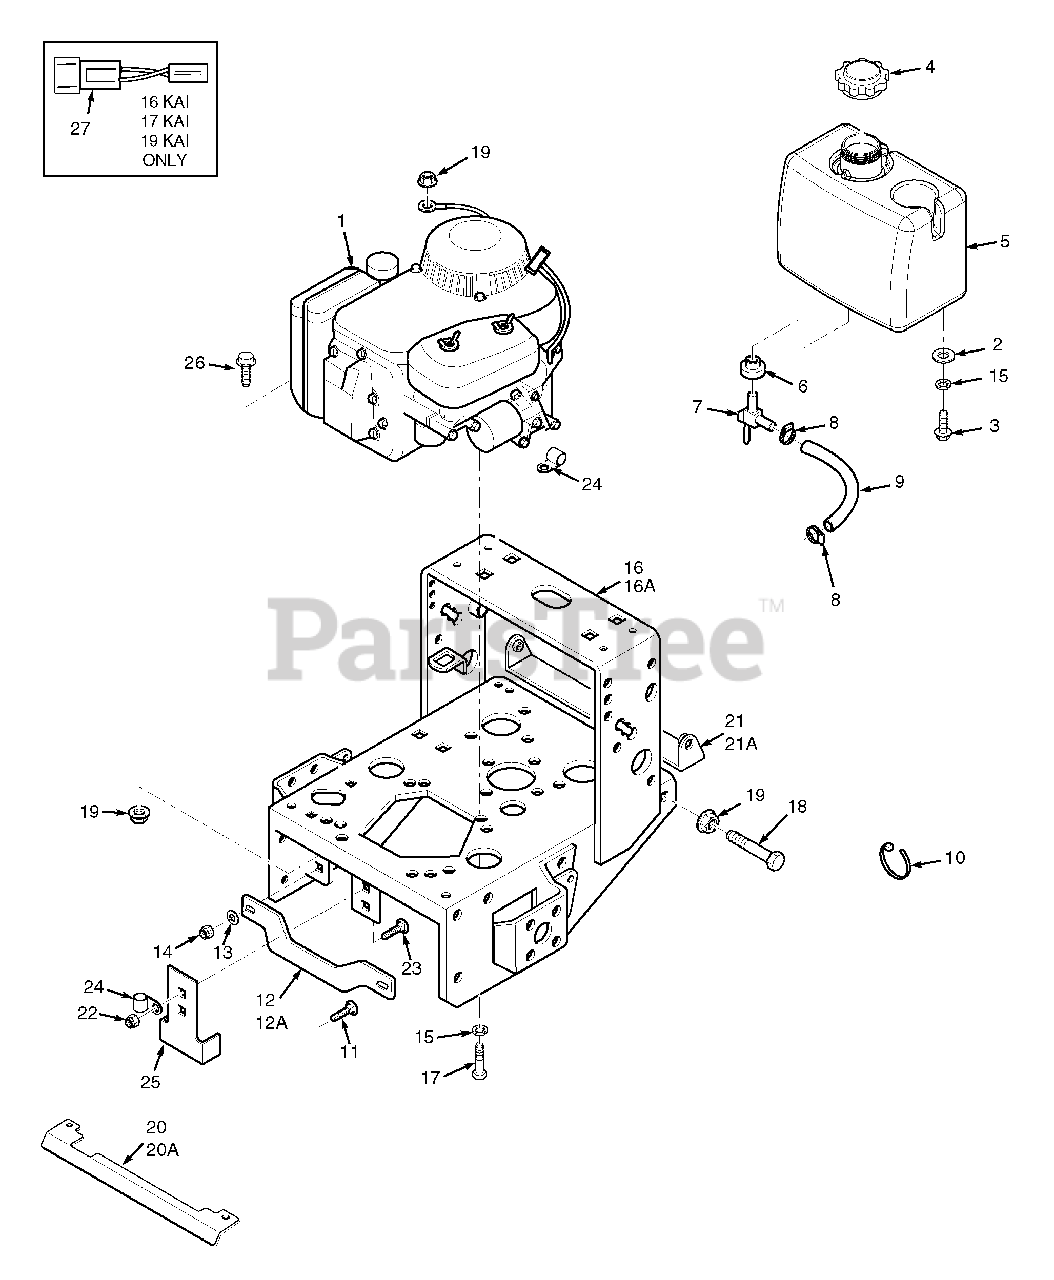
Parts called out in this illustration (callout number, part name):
1	Engine, 17KAI Kawasaki
2	Flatwasher, 5/16 (.375 x .875 x .083)
3	Capscrew, 5/16-18 x 1" Hex Head
4	Cap, Fuel Tank
5	Fuel Tank Assy.
6	Bushing
7	Valve, Fuel Shut-off
8	Clamp, Fuel Hose
9	Fuel Hose, 1/4 ID x 18"
10	Cable Tie
11	Carriage Bolt, 3/8-16 X 1-1/4"
12	Brace, (16" Small Frame)
12A	Brace, (20" Large Frame)
13	Flat Washer .391 x .938 x .105
14	Nut, 3/8-16 Elastic Stop
15	Lock Washer 5/16"
16	Engine Deck, 16" Wide, w/decals
16A	Engine Deck, 20" Wide, w/decals
17	Bolt, 5/16-18 x 1" Serrated Flange Hex Head
18	Bolt, 5/16-18 x 2" Hex Head
19	Nut, 5/16-18 Serr. Flange
20	Heatshield (16" Small Frame)
20A	Heatshield (20" Large Frame)
21	Pulley Guard, 16" Frame
21A	Pulley Guard, 20" Frame
22	Nut, 5/16-18 Elastic Stop
23	Carriage Bolt, 5/16-18 x 1"
25	Clutch Bracket
26	Cap Scrw, 5/16-18 x 1.50" Sr. Flg
27	Wire Hrns. Adapter, 16KAI, 17KAI & 19 KAI
